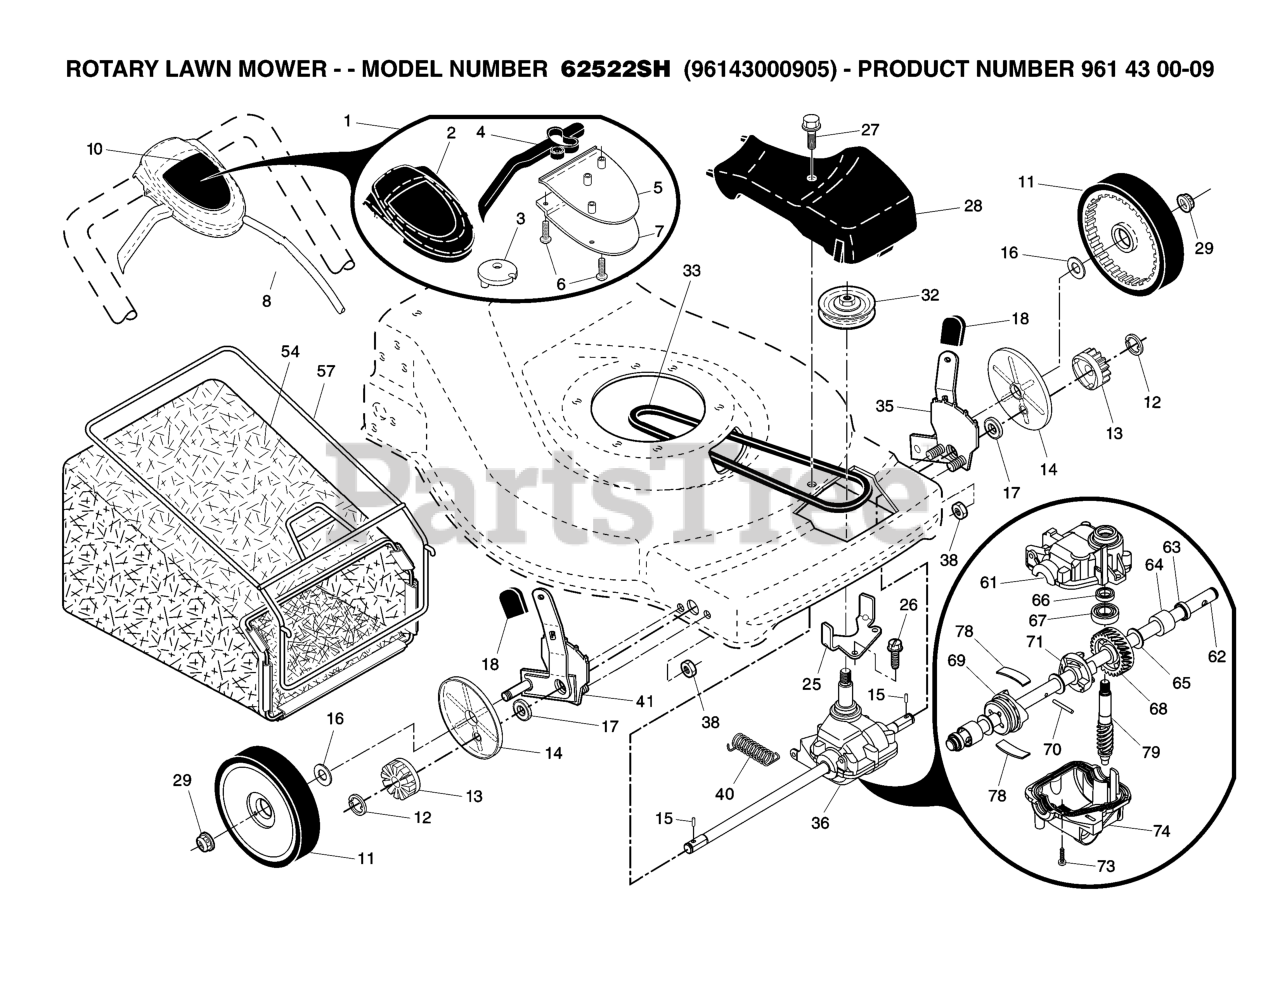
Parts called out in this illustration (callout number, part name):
1	DRIVE CONTROL ASSEMBLY (INCLUD
2	COVER TOP AUTO WALK CONTROL
3	PULLEY
4	LEVER, AUTOWALK DRIVE CONTROL
5	COVER BOTTOM AUTO WLK CONTROL
6	SCREW, PHILLIPS HEAD 10 X 5/8
7	BRACKET.DRIVE.CONTROL.MOUNT.BL
8	CABLE ASSEMBLY, DRIVE
10	DECAL, DRIVE
11	WHEEL.8X1.75.H3SPK.RAD3.GY.BU3
12	E-RING 7/16 RE
13	PINION.14.TEETH.FGD
14	COVER.DUST.WHEEL
15	PAWL.DRIVE
16	WASHER FLUT
17	BEARING
18	KNOB.DELUXE.GRAY
25	BELT KEEPER
27	SCREW, HEX HD TAPPING #10-24 1
28	RP DRIVE COVER
29	NUT.HEX.FLANGE.3/8-16.LO(3 2)
32	RP PULLEY.DRIVE.EZ
33	BELT.DRIVE.FG
35	WHEEL ADJ KIT LH
36	TRANSMISSION.22.VS.FWGD
38	LOCKNUT.NYLOC.1/4-20
41	WHEEL ADJ KIT RH
54	GBAG.8471024T.SIL.HUSQ.BLU
57	FRAME GRASSBAG
61	CASE.UPPER.00254(SERVICE)
62	Shaft, Output
63	SEAL.OUTPUT.SHAFT
66	SEAL INPUT SHAFT
68	GEAR 28 TEETH 36208
69	FIXED DOG CLUTCH
70	PIN.3.50.33733
71	MOVEABLE DOG CLUTCH
74	CASE.BOTTOM.
78	SPRING LEAF
79	SHAFT WORM
